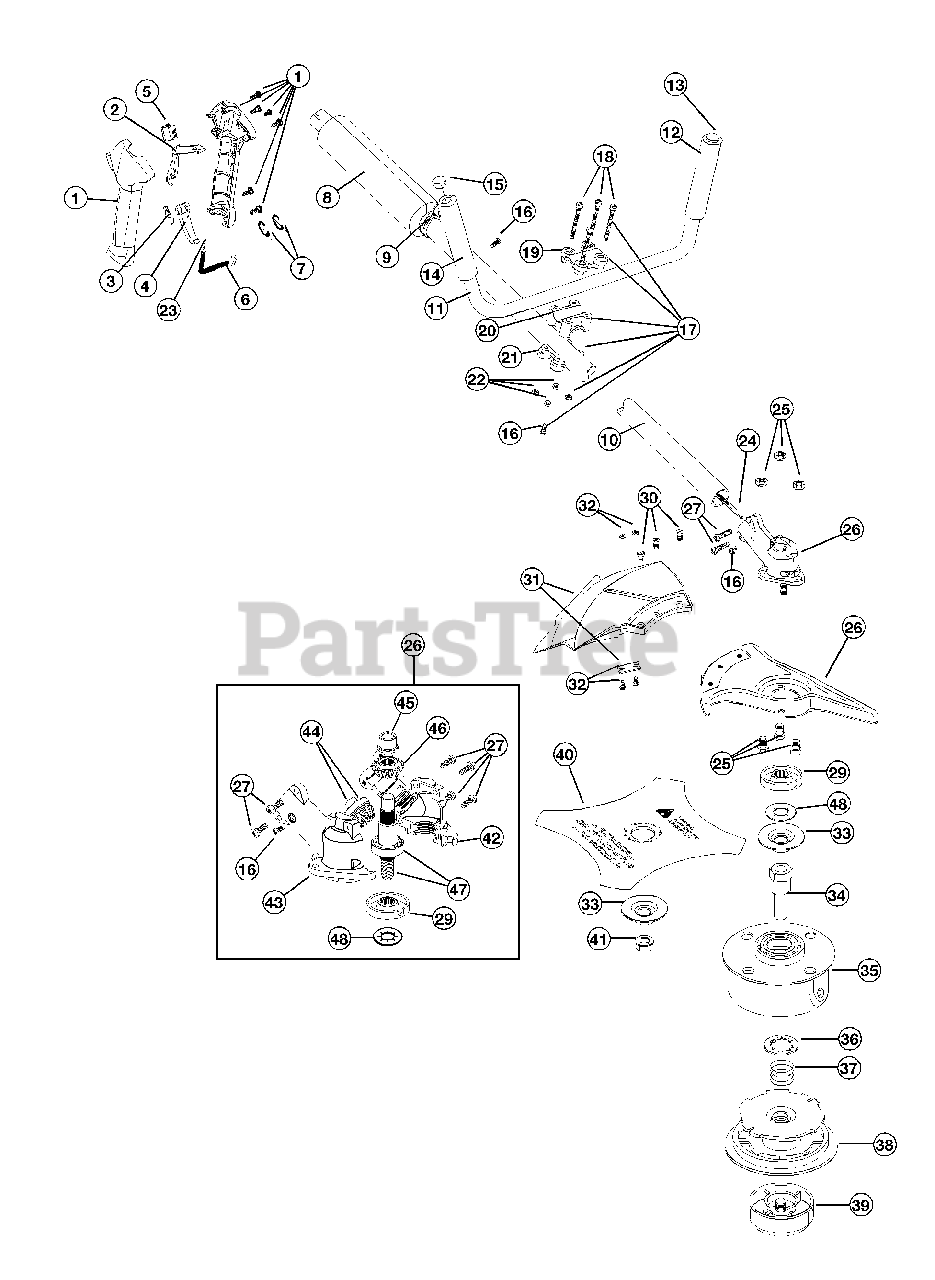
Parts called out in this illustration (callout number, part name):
1	Throttle Housing & Trigger Assm
2	Throttle Trigger Lock-Out
3	Throttle Trigger Spring
4	Throttle Trigger
5	Switch Assembly
6	Wire Cover 1ft
7	Wire Tie
8	Foam Grip & Cover
9	Harness Clip
10	Upper Drive Shaft Housing
11	Bullhorn Handle Assembly
13	Plug
14	Adapter
16	Anti-Rotation Screw
17	Handle Bracket Assembly
19	Upper Handle Clamp
20	Middle Handle Clamp
21	Lower Handle Clamp
23	Throttle Cable
24	Flexible Drive Shaft
25	Shield Mount Screw Assembly
26	2 Piece Gearbox Assembly
27	Gear Box Screw
28	Blade Shield/Shield Mount
29	Blade Driver
30	Shield Mounting Screw
31	Shield and Blade Assembly
32	Blade Assembly
33	Retaining Washer
34	Spool Shaft
35	Outer Spool & Eyelet Assembly
36	Retainer
38	Inner Reel
39	Bump Head Knob Assembly
40	4-Tooth Blade
41	Nut
42	Left Housing
43	Right Housing
44	Pinion Gear Assembly
45	Output Shaft Bushing
46	Output Shaft Gear
47	Output Shaft Assembly
48	Palnut
